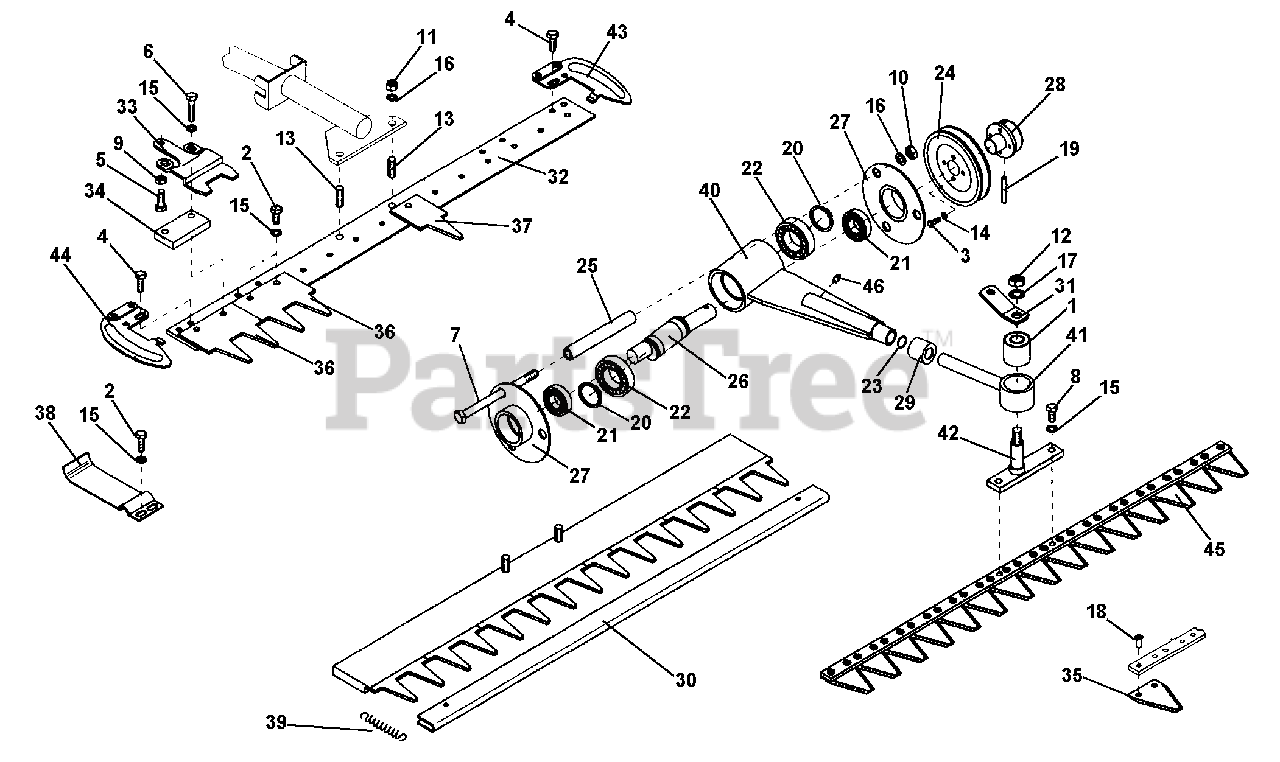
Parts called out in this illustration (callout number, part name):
1	SILENT BLOCK
2	SCREW M8X16
3	SCREW M5X16
4	SCREW M8X14
5	SCREW M8X20
6	SCREW M8X35
7	SCREW M10X120
8	SCREW M8X1X16
11	NUT, SELF LOCKING M10
12	NUT, SELF LOCKING M12
13	STUD M10X30
14	WASHER, FLAT M5.3
15	WASHER M8.4
16	SUPER WASHER M10
17	SUPER WASHER M13
18	RIVET M5.3X14
19	LOCKING PIN M6X45
20	CIRCLIP, EXTERNAL
21	BEARING M20X47X14
22	BEARING M30X55X13
26	ARTICULATING SHAFT
27	BEARING HOLDER
30	BLADE GUARD
31	HOOD BRACKET
32	SLIDE FOR CUTTERBAR
33	BLADE HOLDER
34	BLADE GUIDE BLOCK
35	INDIVIDUAL BLADE
36	DOUBLE FINGER
37	SINGLE FINGER
40	BAR CONTROL
41	ARM, BAR CONTROL
43	R.H. END GUARD
44	L.H. END GUARD
45	BLADE ASSEMBLY
